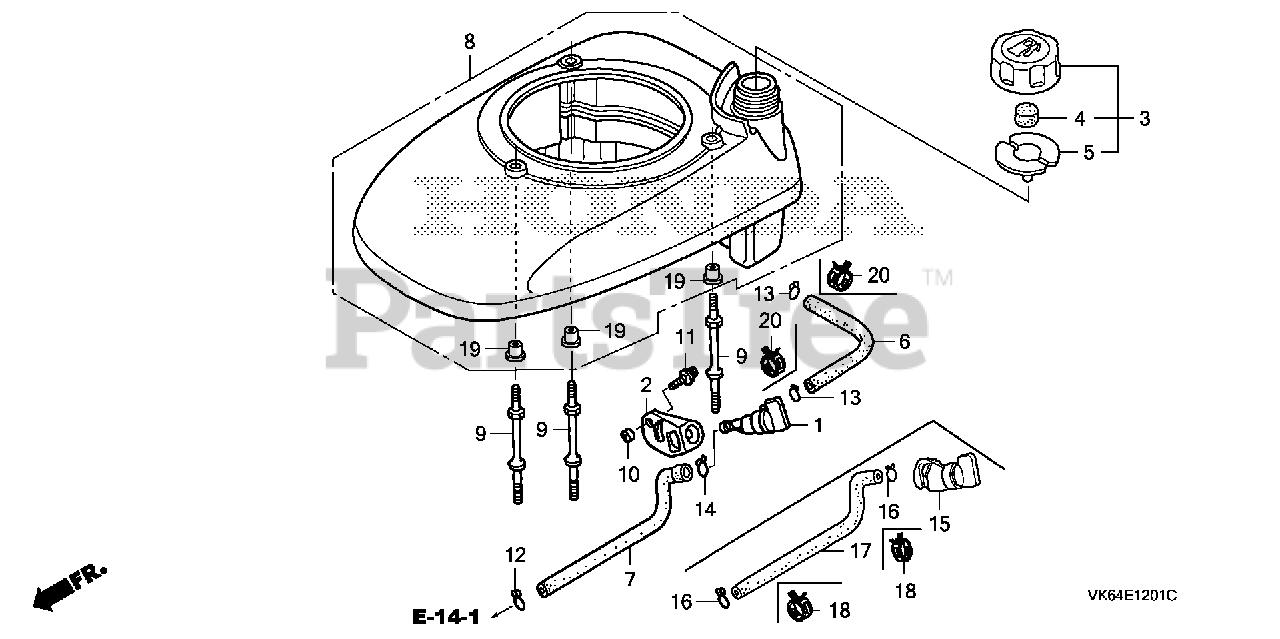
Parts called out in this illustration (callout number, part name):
1	PETCOCK ASSY.
2	BRACKET, PETCOCK
3	CAP ASSY., FUEL TANK
4	SPONGE, FUEL CAP BREATHER
5	GASKET, FUEL CAP
6	TUBE, FUEL TANK
6	TUBE, FUEL (5.3X150) (FKM)
6	BULK HOSE, FUEL (5.5X3000) (Honda Code 5338587). (5.5X150)
7	TUBE, FUEL
8	COVER, FAN *R280* (POWER RED)
9	BOLT, STUD
10	COLLAR, FUEL PETCOCK
11	SCREW-WASHER (5X10)
12	CLIP, TUBE (B8)
13	CLIP, TUBE (B10)
14	CLIP, TUBE (C9)
15	PETCOCK ASSY.
16	CLIP, TUBE (B8)
17	TUBE, FUEL
17	TUBE, FUEL (FKM)
18	CLIP, TUBE (D8)
19	COLLAR, FAN COVER (Honda Code 5580527). (N/A: SEE ASSEMBLY)
20	CLAMP, TUBE (D10)
